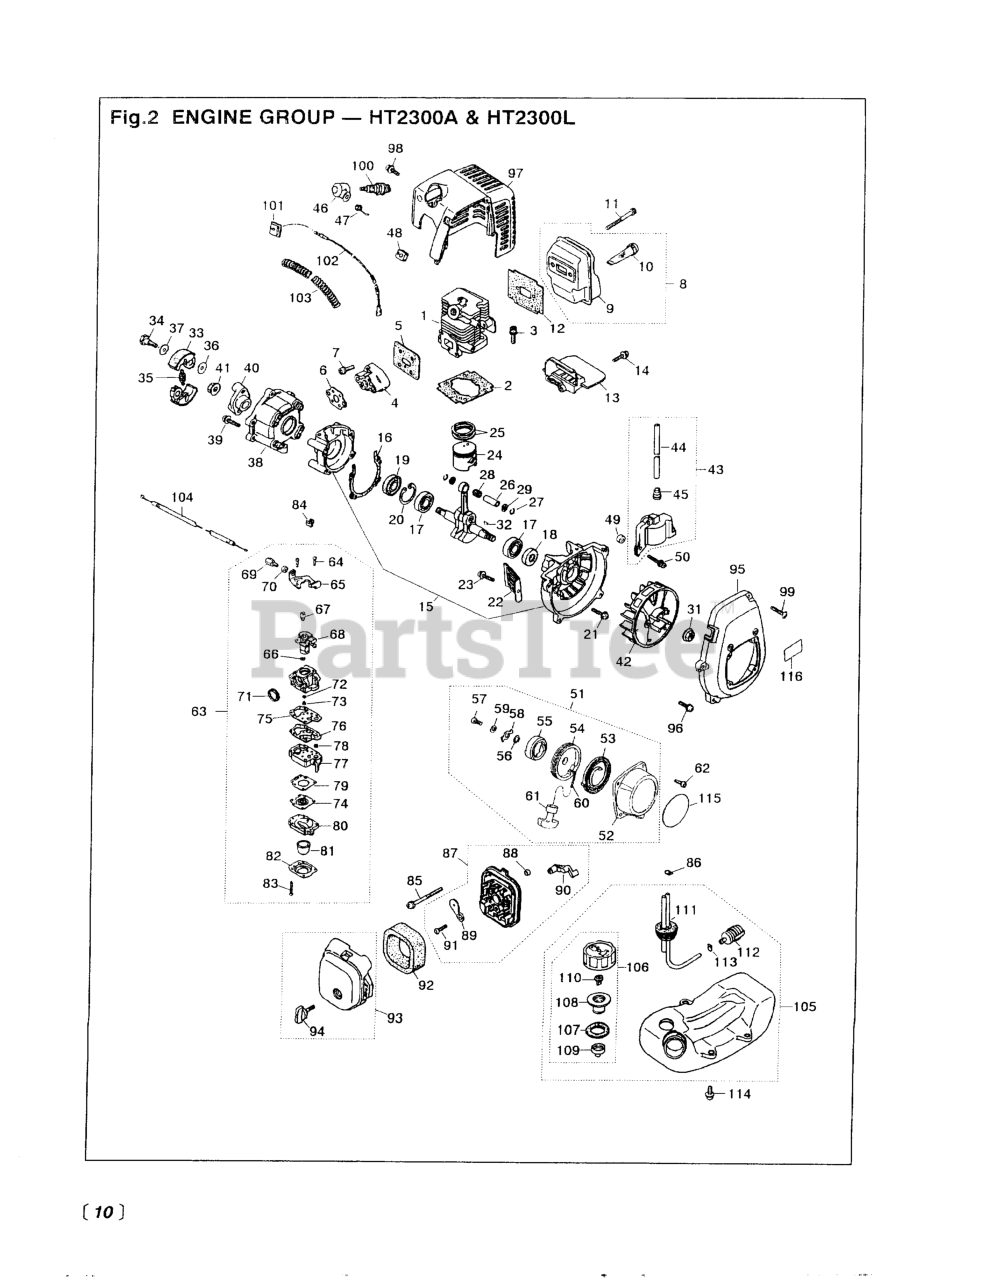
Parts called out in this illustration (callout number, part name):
1	CYLINDER
3	BOLT, M5 X 22
7	SCREW, M5X20 (RPLS.1400-75510)
8	MUFFLER ASSEMBLY
9	MUFFLER
10	ARRESTER (RPLS 5850-15140)
11	BOLT, M5 x 50
12	GASKET, MUFFLER
14	SCREW, M4 X 16
15	CRANKCASE COMP.
17	BEARING
18	SEAL, OIL (RPLS 1100-21210)
19	SEAL, OIL (RPLS 1140-21220)
20	RING, SNAP, M28 x 1.2
21	SCREW, M5 x 30(RPLS 0263-00530
23	SCREW, M5 X 12
26	PIN, PISTON 5x8x26
27	RING, SNAP (RPLS 1101-41320)
29	WASHER
32	KEY
34	BOLT
36	WASHER, FLAT (USE 182303)
38	CASE, CLUTCH
39	SCREW
40	PLATE, CLUTCH
42	ROTOR (RPLS 5601-71110)
44	CORD
45	CAP
47	SPRING
48	GROMMET
50	BOLT
52	CASE, RECOIL
53	SPRING, SPIRAL
56	WASHER
59	WASHER
60	ROPE
62	SCREW, M4 x 12
63	CARBURETOR
64	SCREW
65	BRACKET
66	RING
67	SWIVEL
69	SCREW, CABLE ADJUSTER
70	NUT, CABLE ADJUSTER
71	RING, PACKING
72	RING, O
74	DIAPHRAGM (USE 4810-81260)
75	GASKET, PUMP
76	DIAPHRAGM
77	BODY, PUMP
79	GASKET, DIAPHRAGM
80	BODY, PURGE
81	PUMP, PRIMING
82	COVER, PUMP
83	SCREW
84	CAP, CABLE END
85	SCREW, M5 X 55
86	CLIP
88	SLEEVE
90	LEVER, CHOKE
91	SCREW (REPLACES 50030272)
92	ELEMENT
95	COVER, FAN
96	SCREW, M5X20 (RPLS.1400-75510)
97	COVER, ENGINE(USE-32101)
98	SCREW, M5 x 12
99	SCREW, HOUSING
102	CORD COMP.
104	CABLE COMPL (RPLS-82100)
107	PACKING
109	HOLDER, CAP
110	VALVE (NLA WHEN OUT)
111	PIPE COMPLETE
112	FILTER ASSY
113	CLIP (REPLACES 2841-31280)
114	SCREW
115	LABEL, RECOIL
116	LABEL, FAN COVER
